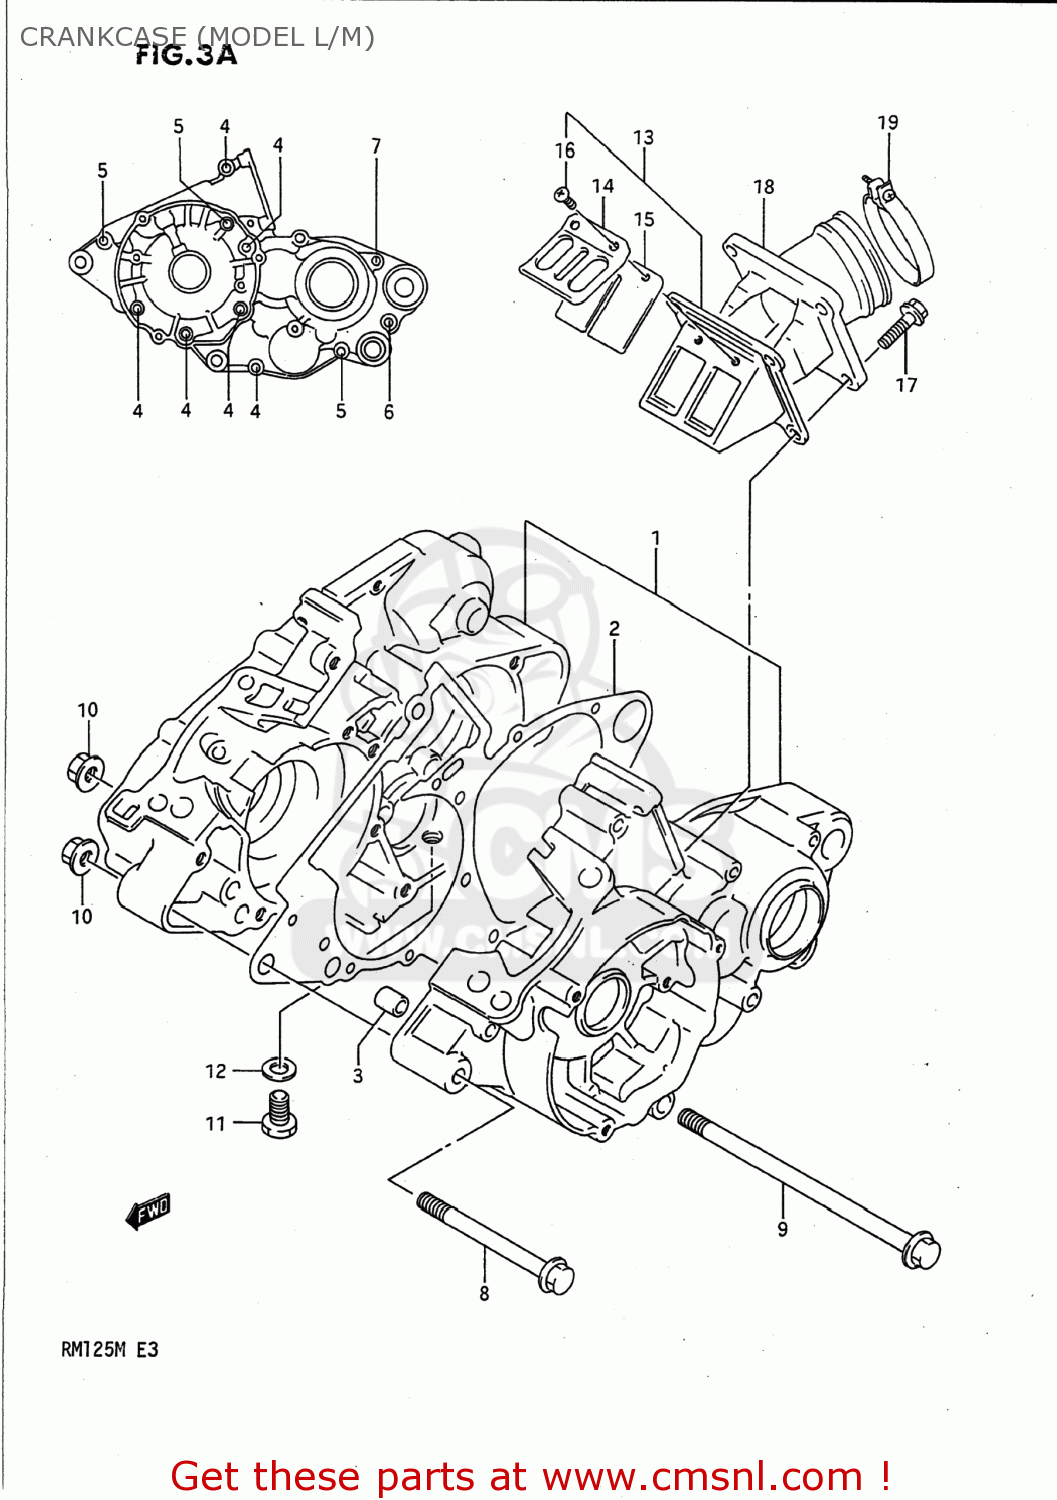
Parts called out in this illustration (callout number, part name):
1	CRANKCASE SET
2	GASKET,CRANKCASE (NAS)
3	PIN
4	BOLT
5	BOLT
6	BOLT
7	BOLT
8	BOLT(8X88)
9	BOLT
10	NUT
11	BOLT,8X16
12	GASKET 8.2X14X1 (NAS)
13	VALVE ASSEMBLY,REED
14	STOPPER,REED VALVE
15	VALVE,REED
16	SCREW
17	BOLT
18	PIPE,INTAKE
19	CLAMP
